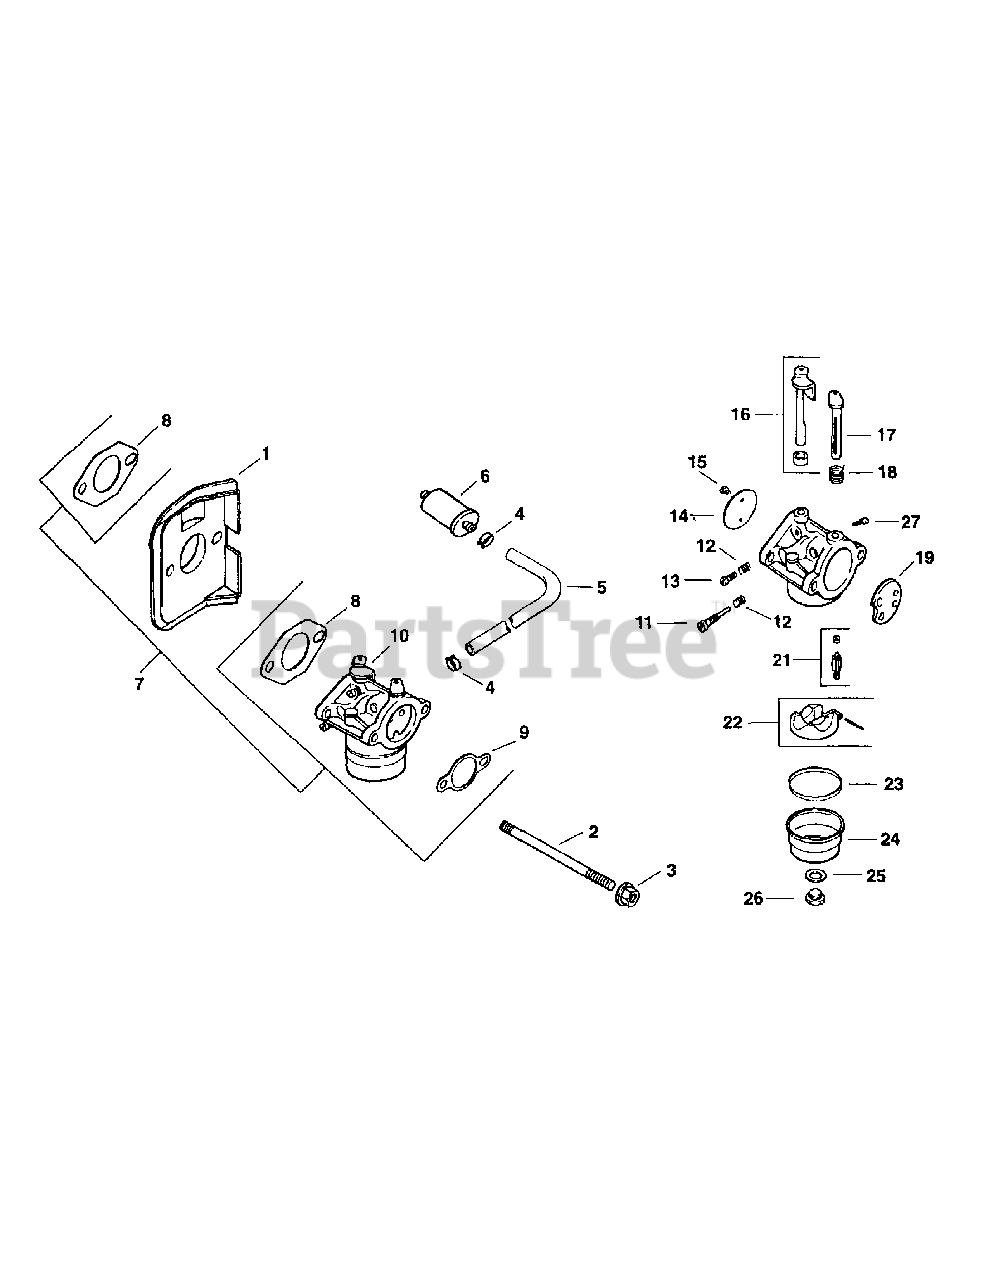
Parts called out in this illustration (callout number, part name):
1	Deflector, Heat
2	Stud, Carburetor
3	Nut, Hex Flange
4	Clamp, Hose
5	Line, Fuel 3"
6	Filter, Fuel
7	Carburetor Kit
8	Gasket, Carburetor
9	Gasket, Air Filter
11	Needle, idle Fuel Adjusting
12	Spring, Idle Fuel & Idle Speed Adj.
13	Screw, Idle Speed Adjusting
14	Plate, Throttle
15	Screw, Valve
16	Shaft, Throttle w/Lever 8 Seal
17	Shaft, Choke
18	Spring, Choke Return
19	Plate, Choke
21	Needle & Seat
22	Float Kit
23	Gasket, Bowl
24	Bowl, Fuel
25	Gasket, Bowl Retainer Screw
26	Screw, Bowl Retainer
